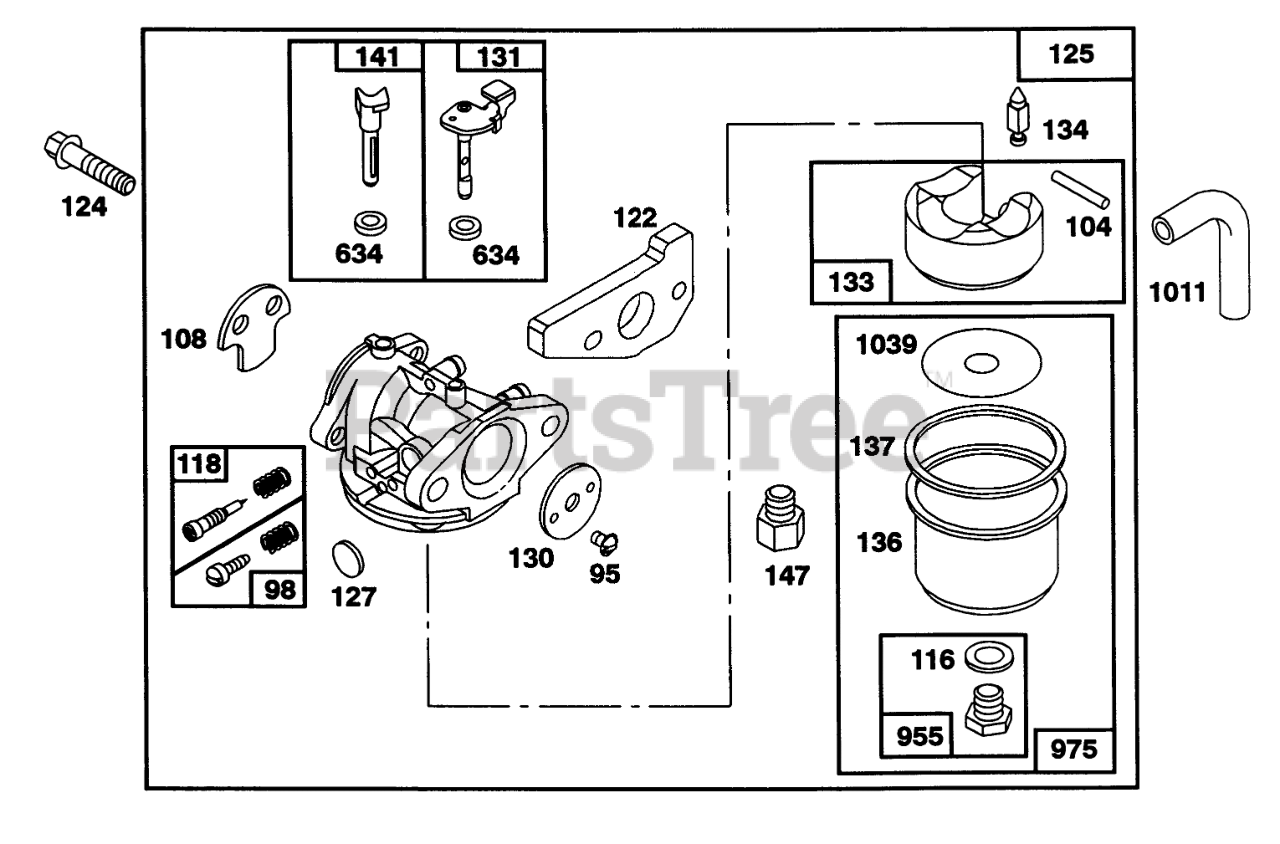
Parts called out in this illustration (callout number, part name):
95	SCREW - ROUND HEAD
98	IDLE ADJUSTING SCREW
104	FLOAT HINGE PIN
108	CHOKE VALVE
116	SEALING GASKET
118	VALVE KIT - NEEDLE
122	ADAPTER ASSEMBLY
124	HEX HEAD SCREW
125	CARBURETOR ASSEMBLY
127	PLUG
130	THROTTLE VALVE
131	THROTTLE SHAFT
133	FLOAT-CARBURETOR
134	Valve-Inlet (Includes Seat)
136	FLOAT BOWL
137	FLOAT BOWL GASKET
141	CHOKE SHAFT
147	JET ADAPTER
634	SEAL WASHER
955	HEX HEAD SCREW
975	CARBURETOR BOWL ASM
977	CARBURATOR GASKET SET
1011	VENT TUBE
1039	FLOAT LIMITER
